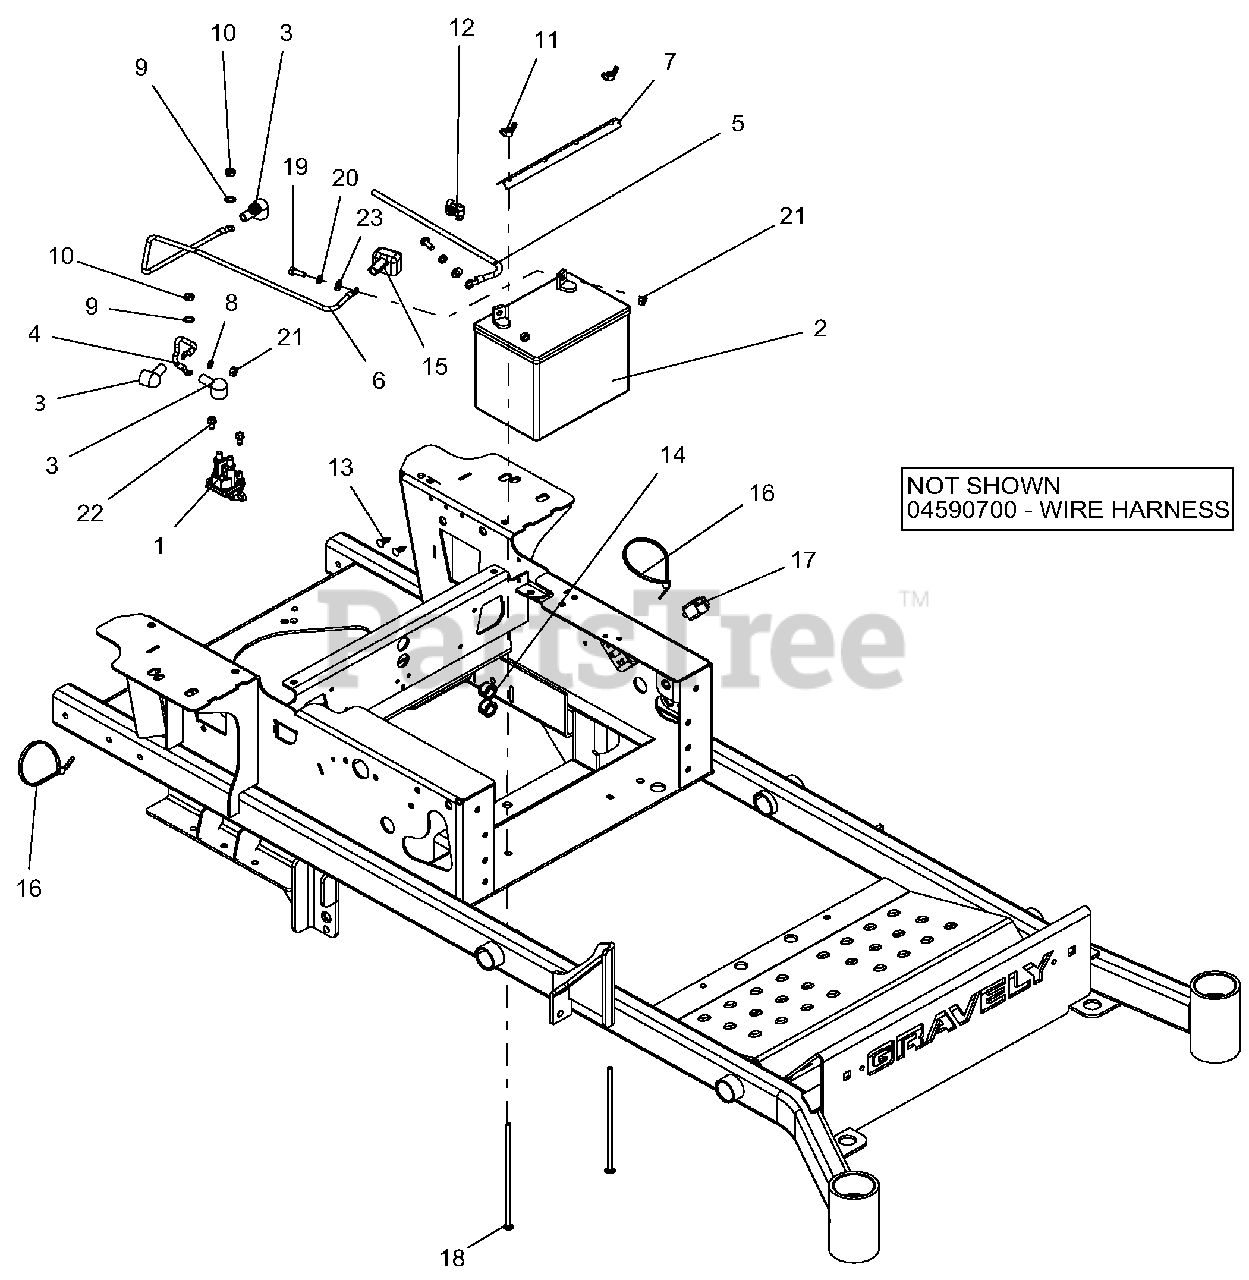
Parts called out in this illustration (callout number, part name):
1	SOLENOID, HP RTV
2	BATTERY,
3	BOOT, EYELET TERMINAL
4	CABLE, POSITIVE BATTERY 9.00"
5	CABLE, NEGATIVE BATTERY 24"
6	CABLE, STARTER .31 X 23.00 X .31
7	HOLD DOWN - BLK
8	@, WSHR-LK-EXT.262X.502X.026 YWZC
9	WSHR-LK-EXT .326X.599X.031 YWZC REV
10	NUT-JAM
11	NUT-LOCKING WING 1/4-20
12	CLIP, T, .31-.38
13	RIVET, .25 NYLON PANEL
14	BUSH, PANEL SNAP .687X.875X.56
15	INSULATOR
16	CABLE, TIE 5.50 LG
17	SWITCH, SINGLE POLE N.O.
18	BLT-RDHDSQNK .25-20X7.50 G2 YWZC
19	BLT-HEX .25-20X.75 GR5 YWZC
20	WSHR-LK .25X.062 REG YWZC
21	NUT-HEX .25-20 YWZC
22	SCR-TAP .25-20X.50 HWH TR YWZ
23	WSHR-FL-STL.281X.62X.065 YWZC
